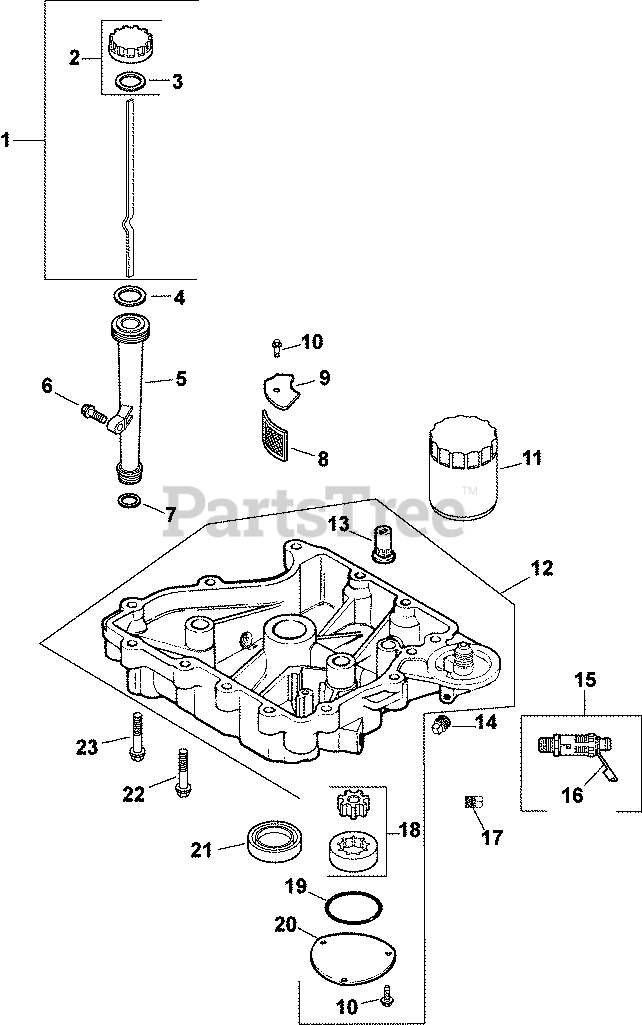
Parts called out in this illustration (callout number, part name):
1	DIPSTICK/CAP ASSY (YELLOW) - DISCONTINUED
2	KIT, OIL FILL CAP (YELLOW)
3	O-RING, DIPSTICK
4	O-RING, UPPER OIL FILL TUBE
5	TUBE, OIL FILL USE 25 123 07-S
6	SCREW, FLG THD FRM M5X.8X20-(#25086399S)
7	O-RING, LOWER OIL FILL TUBE
8	SCREEN, OIL-USE 24 162 26-S
10	SCREW,FLG THD FRM M5X0.8X16-(#25086398S)
11	OIL FILTER
12	PAN, OIL
13	VALVE, OIL PRESSURE RELIEF
14	PLUG, SQ HD PIPE 3/8"
15	CAP, OIL DRAIN VALVE
16	KIT, OIL DRAIN VALVE
17	PLUG, PIPE 1/8 NPTF-SQ.HD.
18	PUMP ASSEMBLY, OIL - DISCONTINUED
19	O-RING (2.5" DIA)
20	COVER, OIL PUMP
21	SEAL, OIL
22	SCREW, HEX FLANGE -USE 24 086 17-S
23	SCREW, FLG M8X1.25X45
